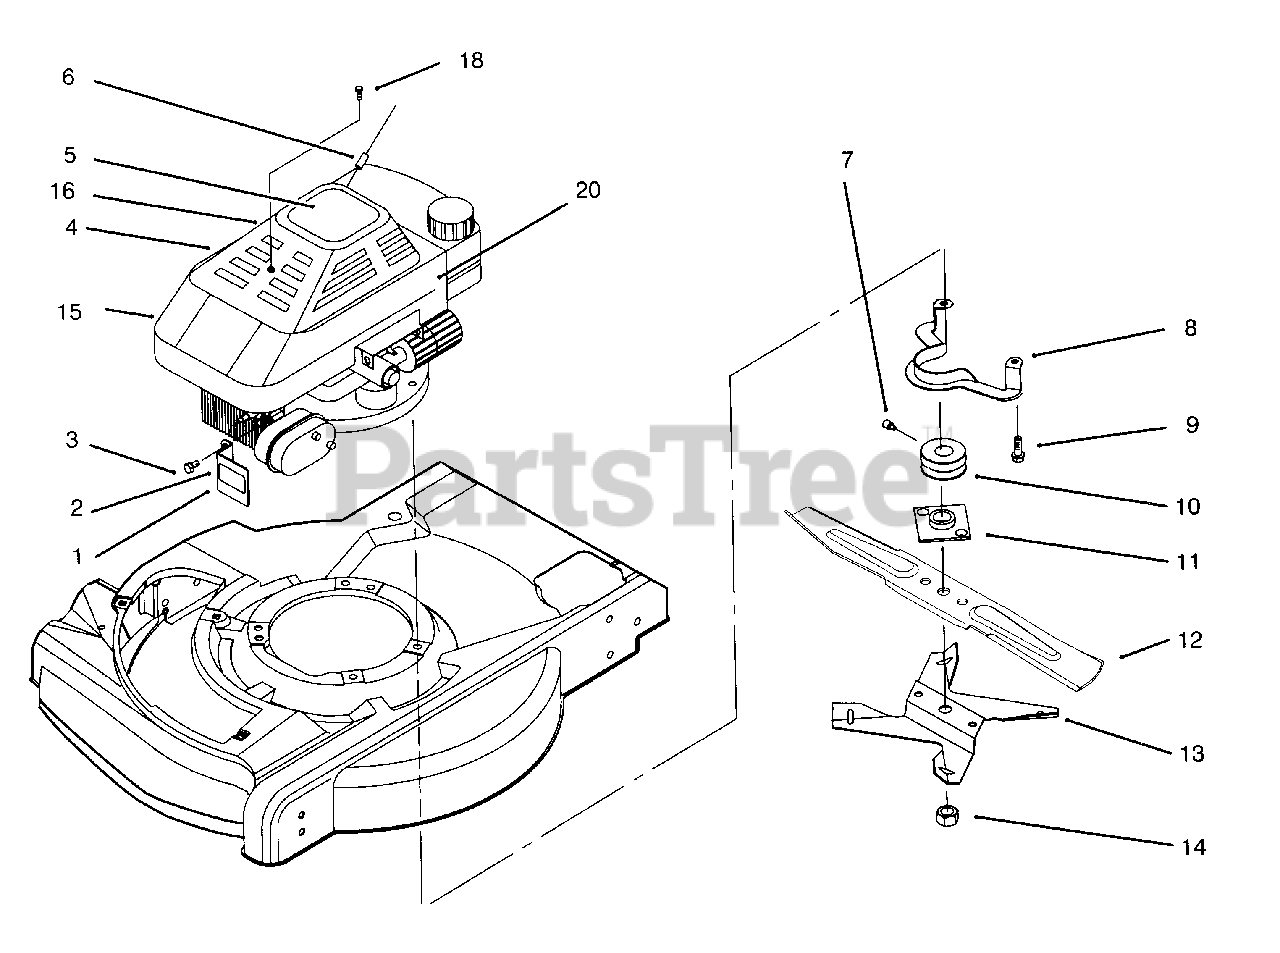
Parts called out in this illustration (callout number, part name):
1	Guard-Muffler (Incl. Ref.#2)
2	Decal-Warning
4	Engine-4 Cycle
5	Decal-Shroud (Model No. 10202 & 10210 Only)
6	Stop-Rope
7	Screw-Set (Model No. 10302 & 10310 Only)
8	Guide-Belt (Model No. 10302 & 10310 Only)
9	Screw-Engine Mount
10	Pulley-Engine (Model No. 10302 & 10310 Only)
11	Plate & Collar Ass'y
12	Blade-21"
13	Fan-Mulching
14	Nut-Blade
15	Shroud-Engine
16	Cover-Recoil
20	Decal-Oil
